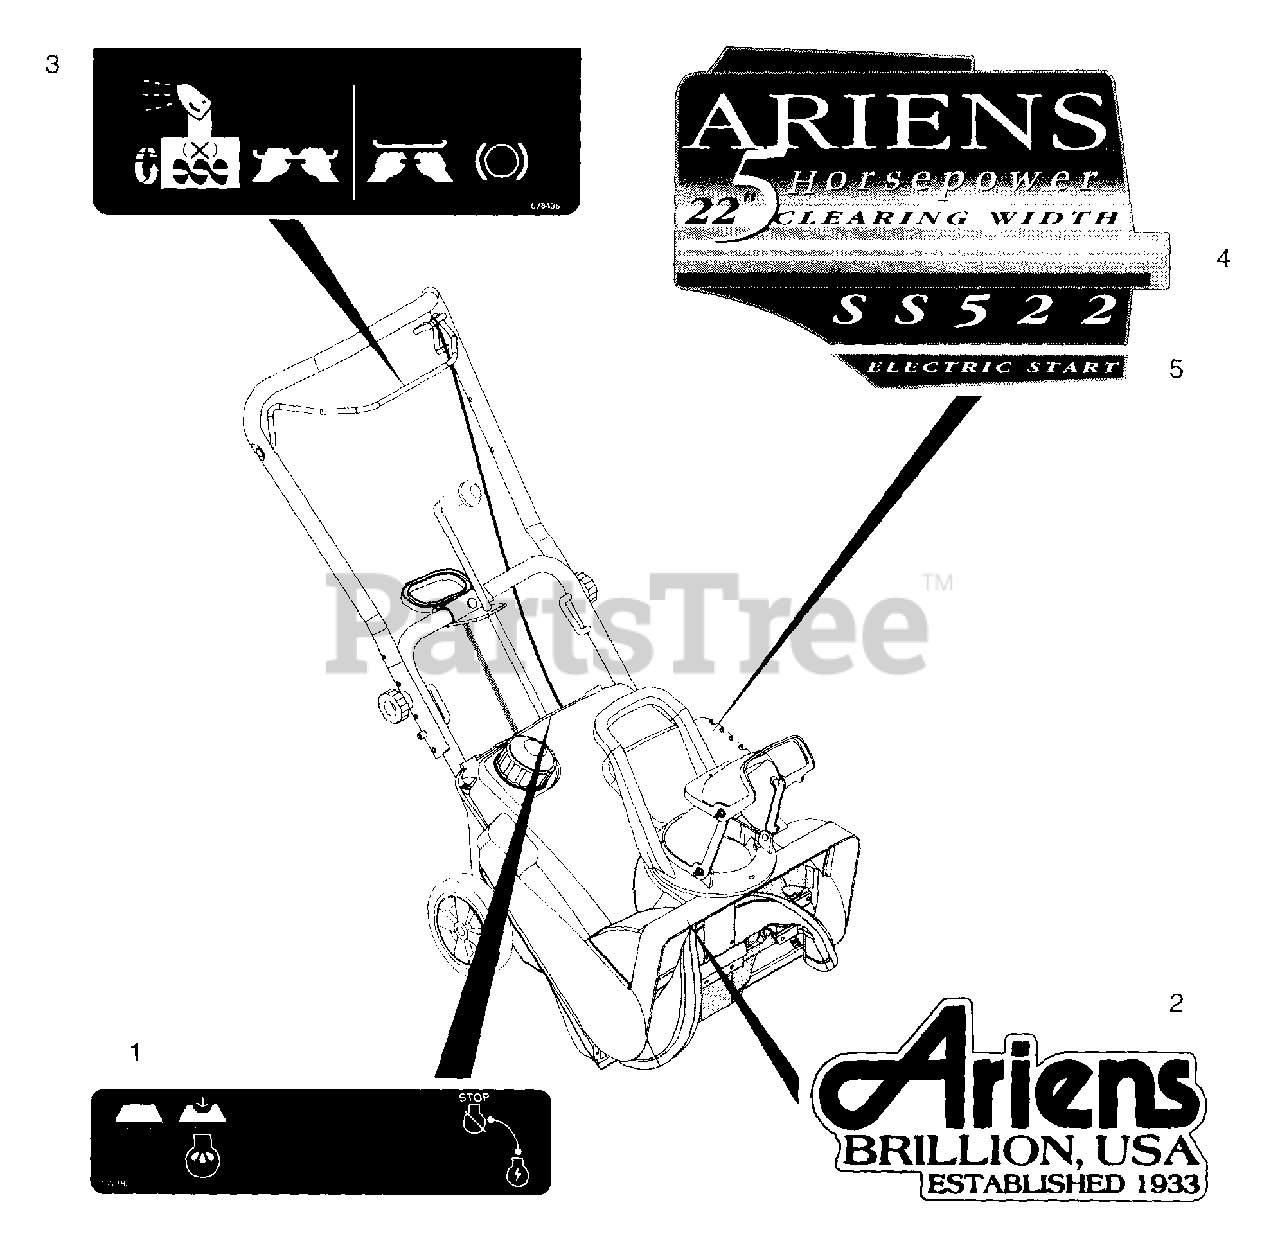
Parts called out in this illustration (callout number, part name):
1	DECAL-PANEL
2	DECAL-LESCO
3	DECAL-AUGER/IMPELLER BAIL
4	SET-DECAL 5 HP ELEC
